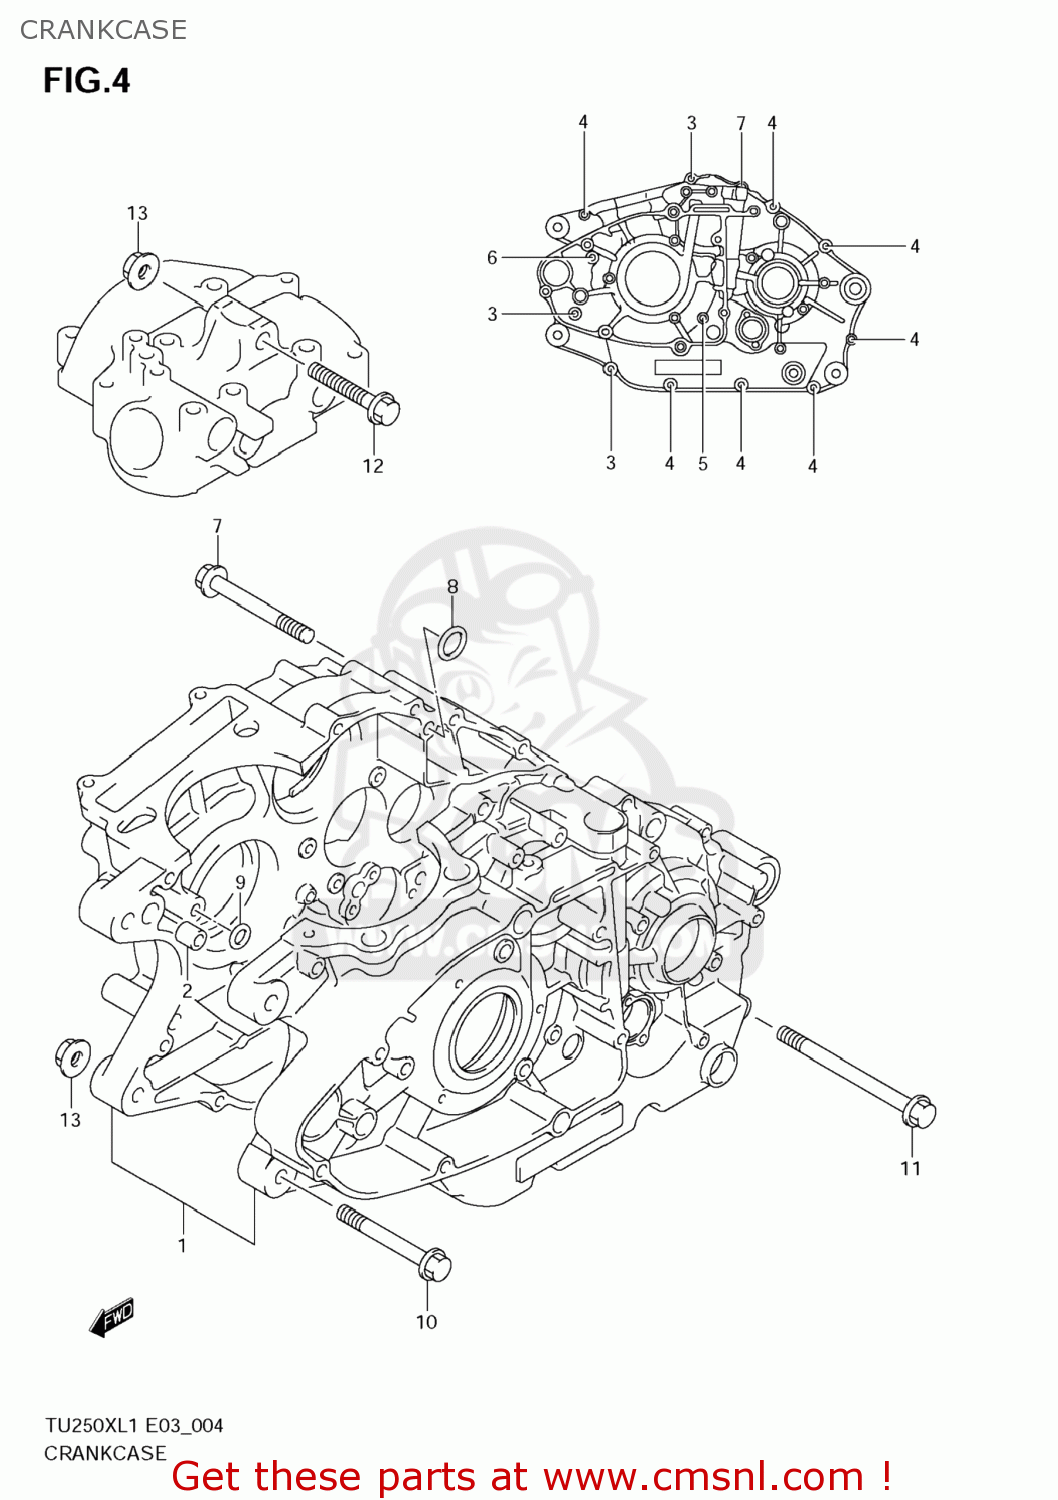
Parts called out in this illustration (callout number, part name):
1	CRANKCASE ASSY
2	PIN
3	BOLT
4	BOLT
5	BOLT
6	BOLT
7	BOLT
8	O RING(D:1.9,ID:9.8)
9	O RING(D:1.9,ID:6.8)
10	BOLT(8X67)
11	BOLT(8X105)
12	BOLT(8X50)
13	NUT
